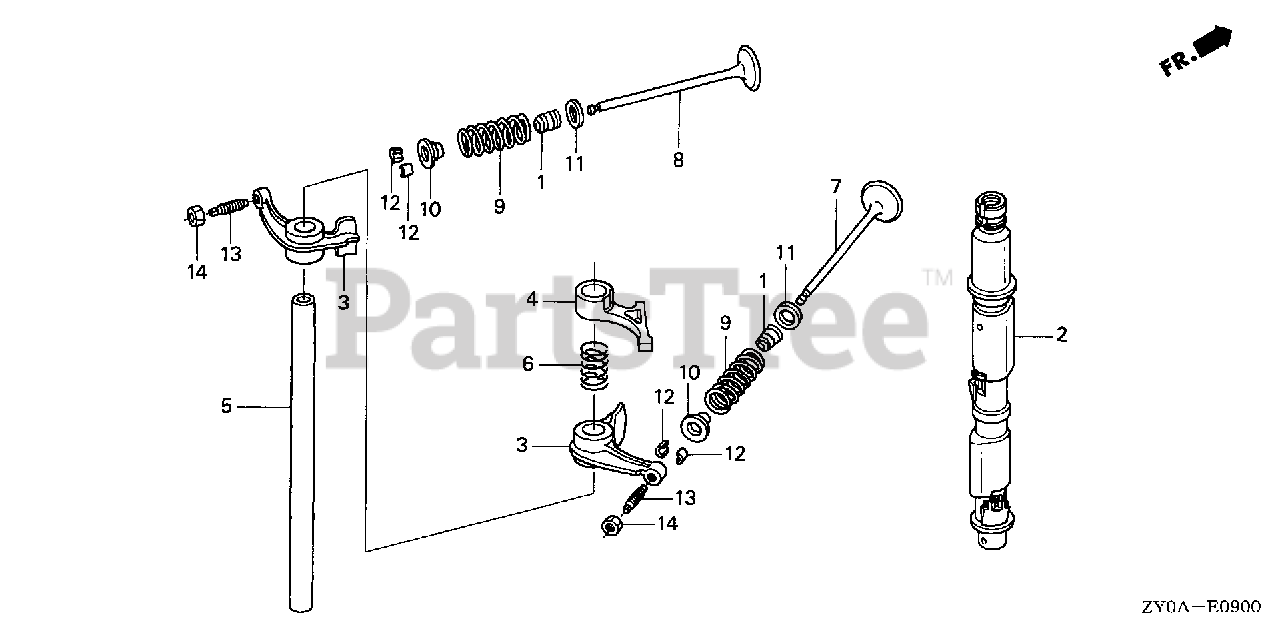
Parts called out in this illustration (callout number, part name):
1	SEAL, VALVE STEM (ARAI)
3	ARM, VALVE ROCKER
4	ARM, FUEL PUMP ROCKER
5	SHAFT, ROCKER ARM
6	SPRING, ROCKER ARM
7	VALVE, IN.
8	VALVE, EX.
9	SPRING, VALVE
10	RETAINER, VALVE SPRING
11	SEAT, VALVE SPRING
12	COTTER, VALVE
13	SCREW, TAPPET ADJUSTING
14	NUT, TAPPET ADJUSTING
